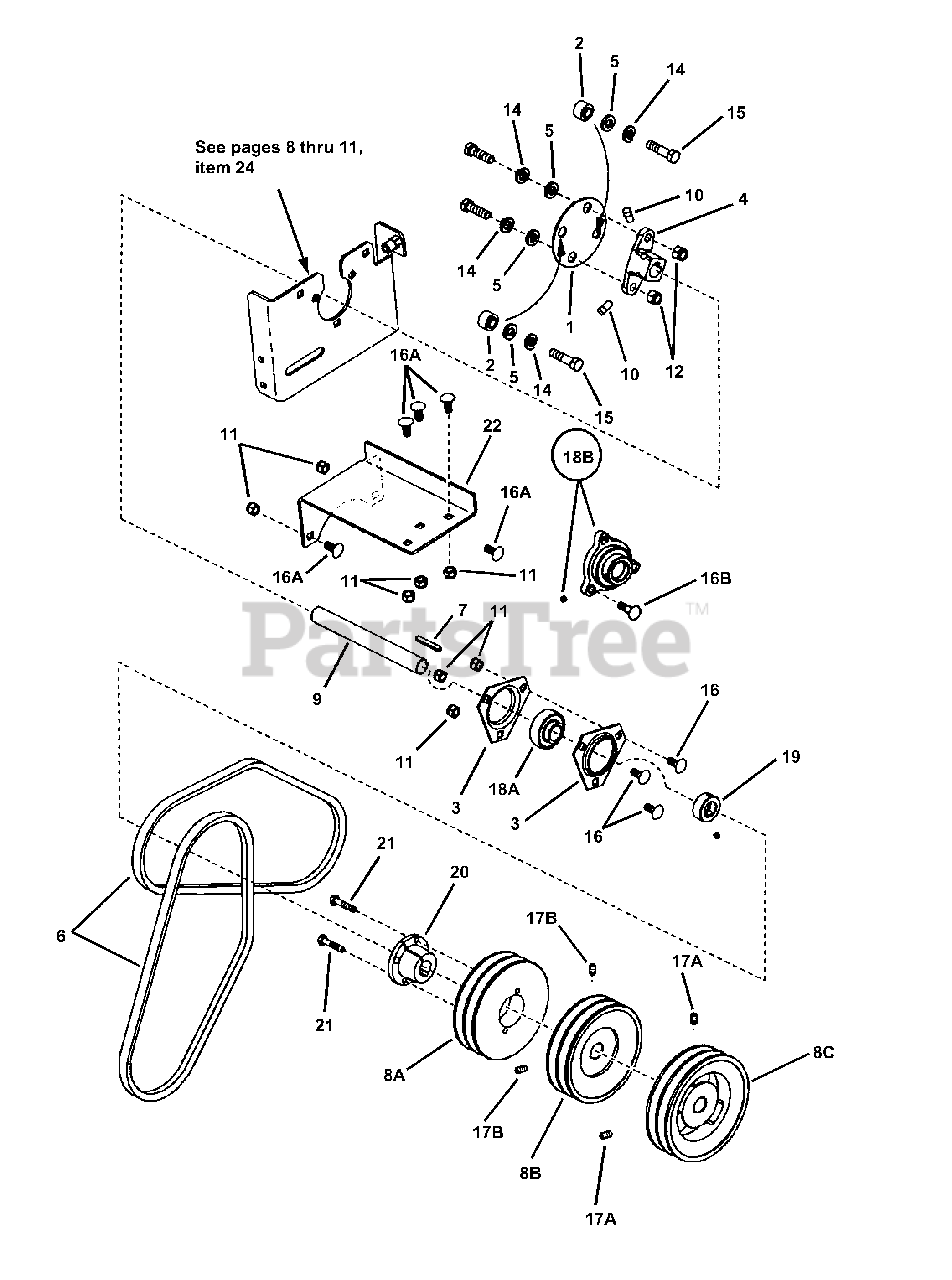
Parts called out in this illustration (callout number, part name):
1	DISC, Flexible
2	SPACER, Coupling
3	FLANGE, Bearing
4	HUB, Drive Shaft Adapter
5	WASHER, 13/32 I.D. x 3/4 O.D., Flat
6	BELT, Traction Drive (AX Cogged, 34.35 Eff. Length)
7	KEY, 3/16 x 1-1/2" Square
8A	PULLEY, Dual V-Groove (4.95" O.D.)
8B	PULLEY, Dual V-Groove (4.95 O.D.)
8C	PULLEY, Dual V-Groove (5.45 O.D.)
9	DRIVE SHAFT, 3/4" Upper
10	SET SCREW, 5/16-18 x 1/2" Square Head
11	NUT, 5/16-18 HEX NYLON LOCK
12	NUT, 3/8-16 HEX NYLON LOCK
14	WASHER, 3/8" SPLIT LOCK
15	SCREW, 3/8-16 x 1-1/2" Hex Head Cap, Grade 5
16A	BOLT, 5/16-18 x 3/4", Carriage, Grade 5 (Models MZM2200K, MZM2300K & ZM2501KH)
16B	BOLT, 5/16-18 x 1-1/4" Square Neck Carriage Gr. 5
17A	SCREW, 5/16-18 x 5/8", Socket-Head
17B	SET SCREW, 5/16-18 x 3/4" Square Head
18A	BEARING
18B	ASSEMBLY, Flange/Bearing/Lock Collar
19	LOCK COLLAR, 3/4" I.D.
20	PULLEY HUB, Taper-Lock
21	SCREW, 1/4-20 x 1-1/4" Hex Head Cap
22	SUPPORT, Bearing Mount
